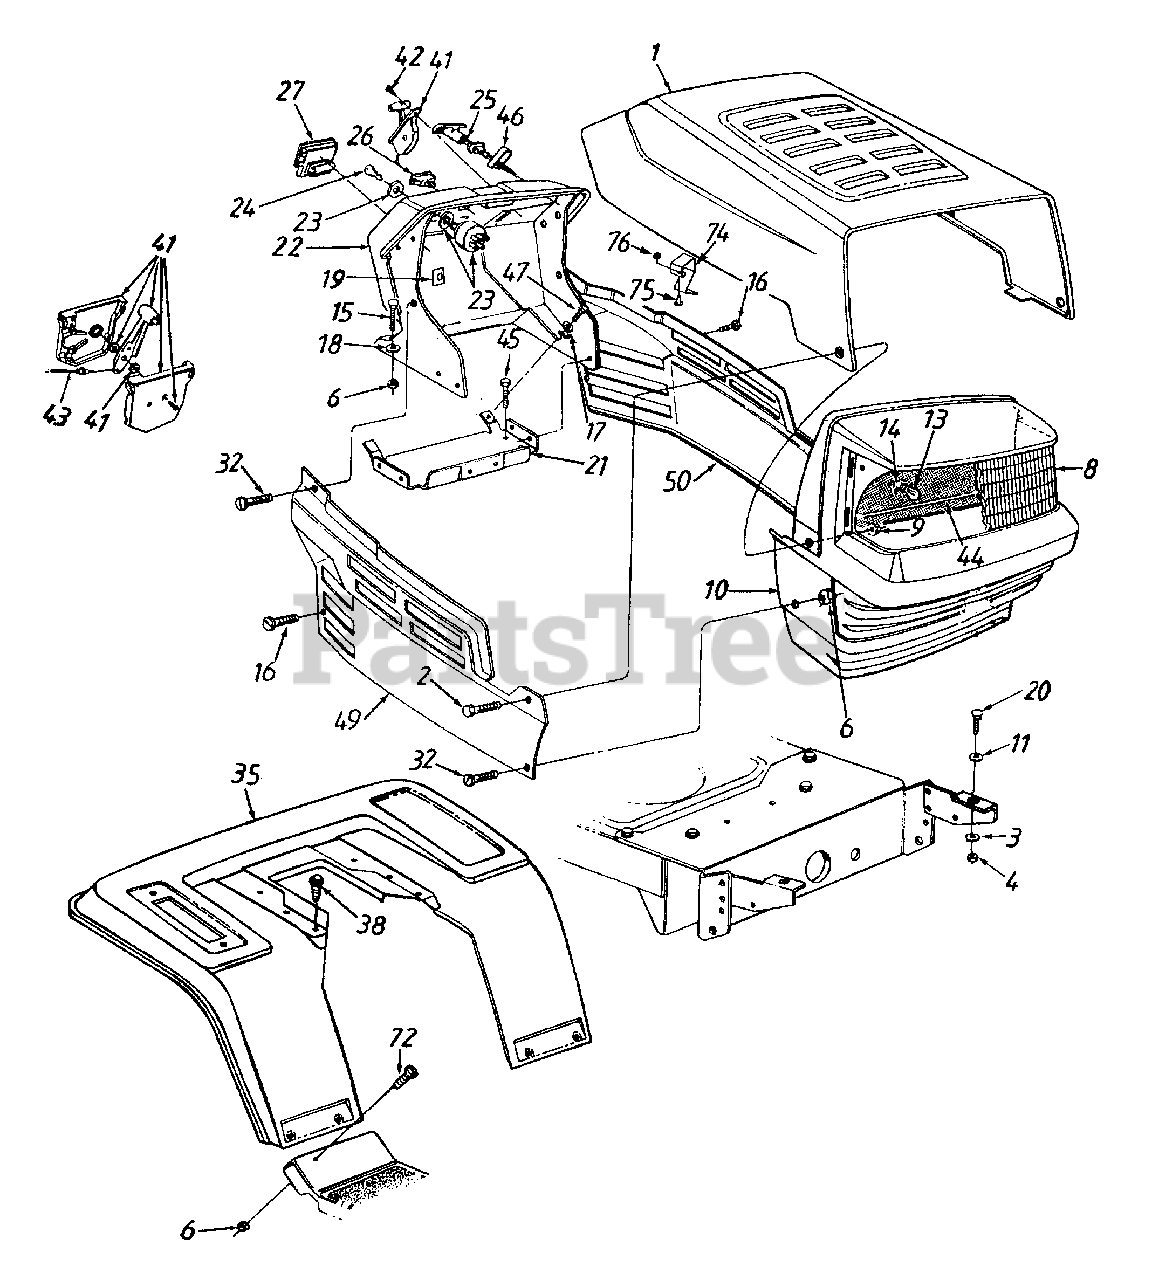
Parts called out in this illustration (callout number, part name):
3	Lock Washer 5/16" I.D.
4	Hex Nut 5/16-18 Thd.
6	Hex Sems Nut 1/4-20 Thd.
8	Headlight Lens w/o Logo
9	Flange Lock Nut 1/4-20 Thd.
10	Grille
11	Flat Washer .344" I.D. x 1" O.D.
13	Lamp
14	Socket
15	Carriage Bolt 1/4-20 x .75" Lg.
16	Hex Wash. Hd. TT-Tap Scr. 1/4-20 x .5" Lg.
17	Flat Washer .281" I.D. x .73" O.D.
18	Bolt Retainer 1/4" I.D.
19	Speed Nut 1/4-20 Thd.
20	Hex Bolt 5/16-18 x .75" Lg. (Gr.5)
23	Ignition Switch
24	Ignition Key
25	Choke Control 23" Lg.
26	Light Switch
27	Ammeter
32	Pan Hd. Scr. 1/4-20 x .75" Lg.
41	Throttle Box Assembly
42	Truss Mach. AB-Tap Scr.#10 x .5" Lg.
43	Throttle Control Wire 18.5" Lg.
44	Grille Reflector Label
45	Hex Wash. Hd. B-Tap Scr. 5/16-18 x .5" Lg.
46	Choke Retainer
47	Hex TT-Tap Scr. 1/4-20 x .75" Lg.
74	Hood Latch
75	Hex Sems Nut 10-24 Thd.
76	Truss Mach. Scr. 10-24 x .5" Lg.
